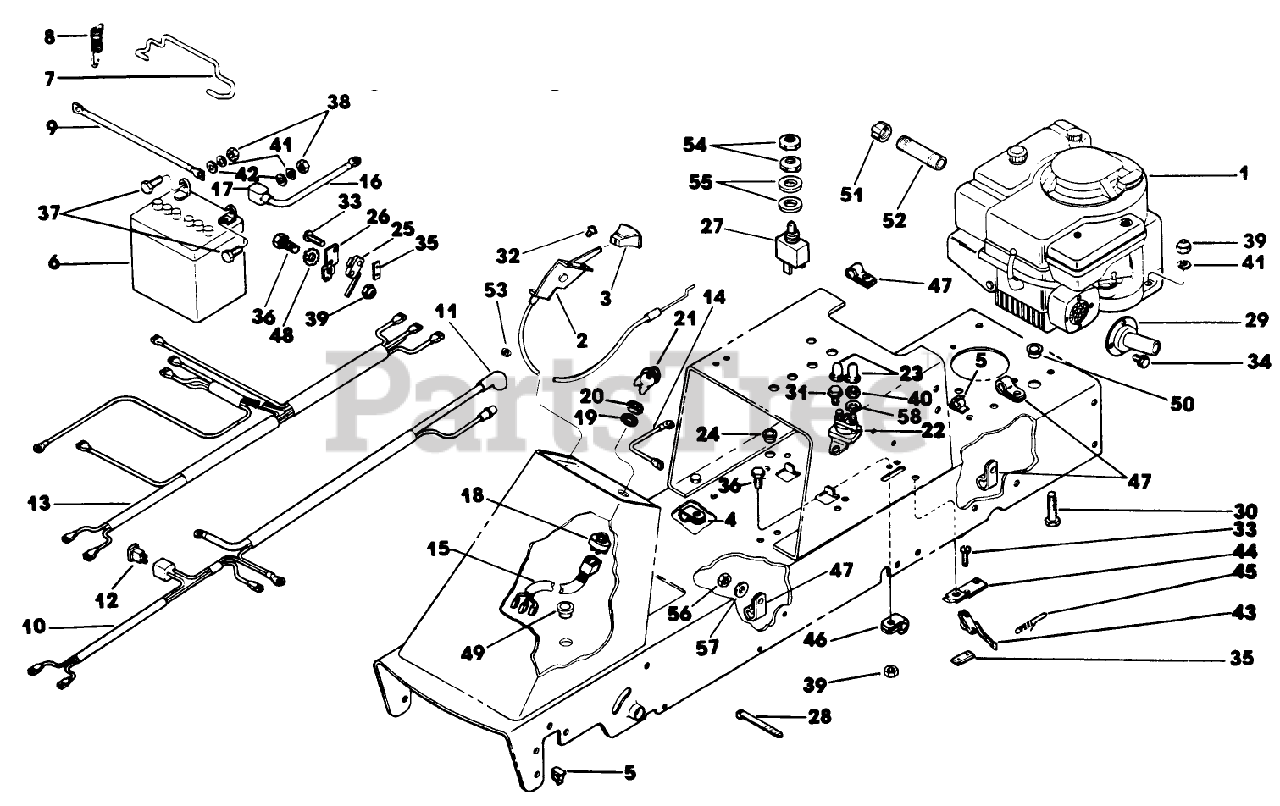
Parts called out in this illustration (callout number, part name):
11	Terminal Cover
28	Cable-Tie
41	Lock Washer 5/16 Plated
